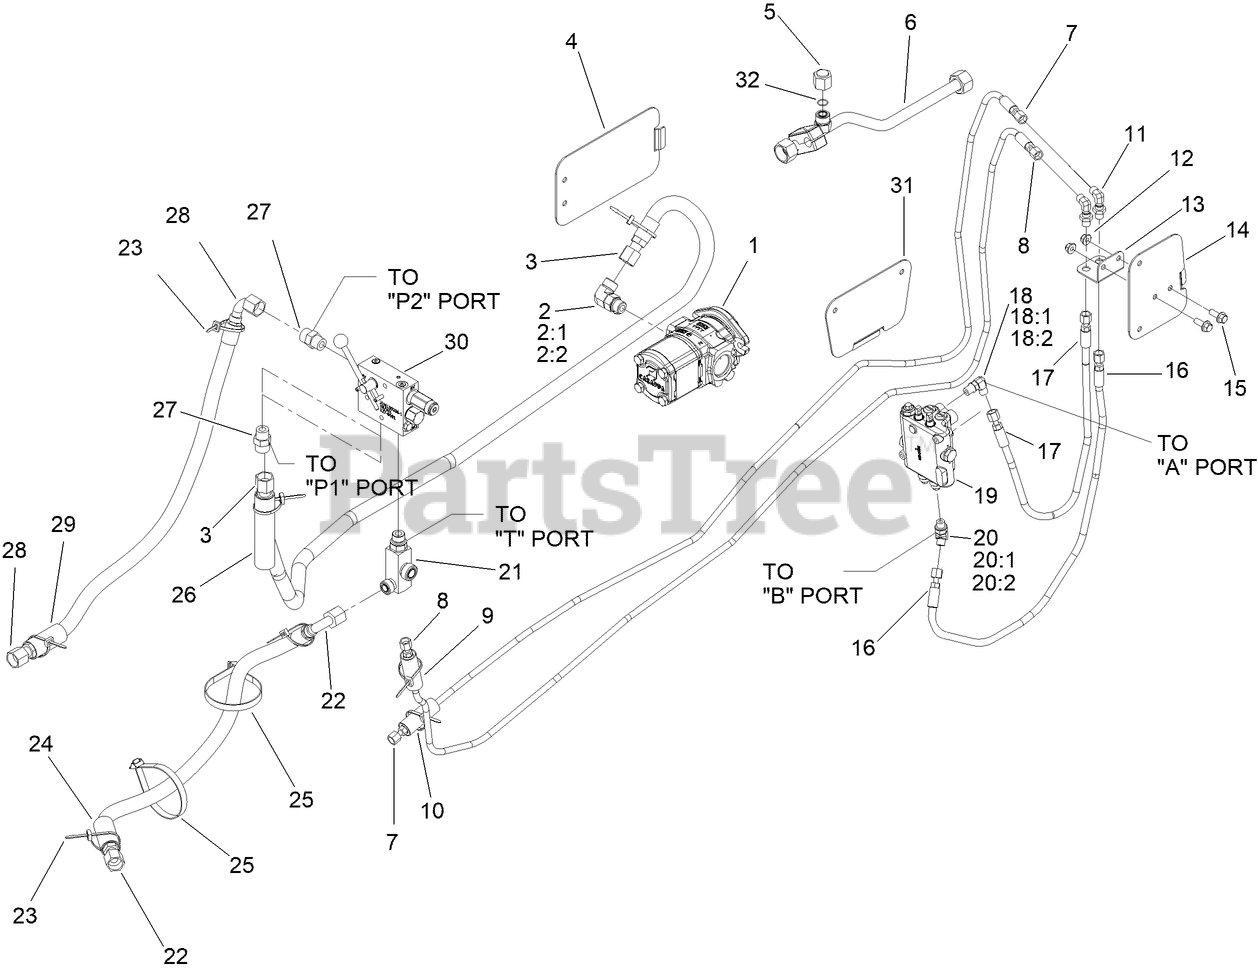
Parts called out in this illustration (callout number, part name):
1	PUMP TANDEM (1.29/.44 CIR)
2	FITTING-ELBOW, 90 DEG
2:1	O-RING
2:2	O-RING
3	HOSE (10OFX-64"-3000)
4	COVER-HYRDABORER (TORO RED)
6	HARDLINE (-12 RETURN TO COOLER)
7	HOSE (04OFX-82"-3000)
8	HOSE (04OFX-92.5"-3000)
9	ABRASION SLEEVE (1.00" X 92")
10	ABRASION SLEEVE (1.00" X 82")
11	BK CONNECTOR (04O-04O90BK)
12	NUT-HF, NI
13	PLATE-BULKHEAD
14	COVER-SELECTOR (TORO RED)
15	SCREW-HHF
16	HOSE (04OFX-32"-3000)
17	HOSE (04OFX-27"-3000)
18	FITTING-ELBOW, 90 DEG
18:1	O-RING
18:2	O-RING
19	HYD STEERING VALVE ASM
20:1	O-RING
20:2	O-RING
21	CONNECTOR (10S-10O-12O)
22	HOSE (10OFX90S-33"-3000)
23	TIE-CABLE
24	ABRASION SLEEVE (1.25" X 33")
25	CABLE TIE (1/2") 20" LG
26	ABRASION SLEEVE (1.25" X 64")
27	CONNECTOR (10S-10O)
28	HOSE (10OFX90S-36"-3000)
29	ABRASION SLEEVE (1.25" X 37")
30	VALVE-CONTROL, VIBE PLOW
31	COVER-TRENCHER (TORO RED)
32	O-RING (016 D90)
